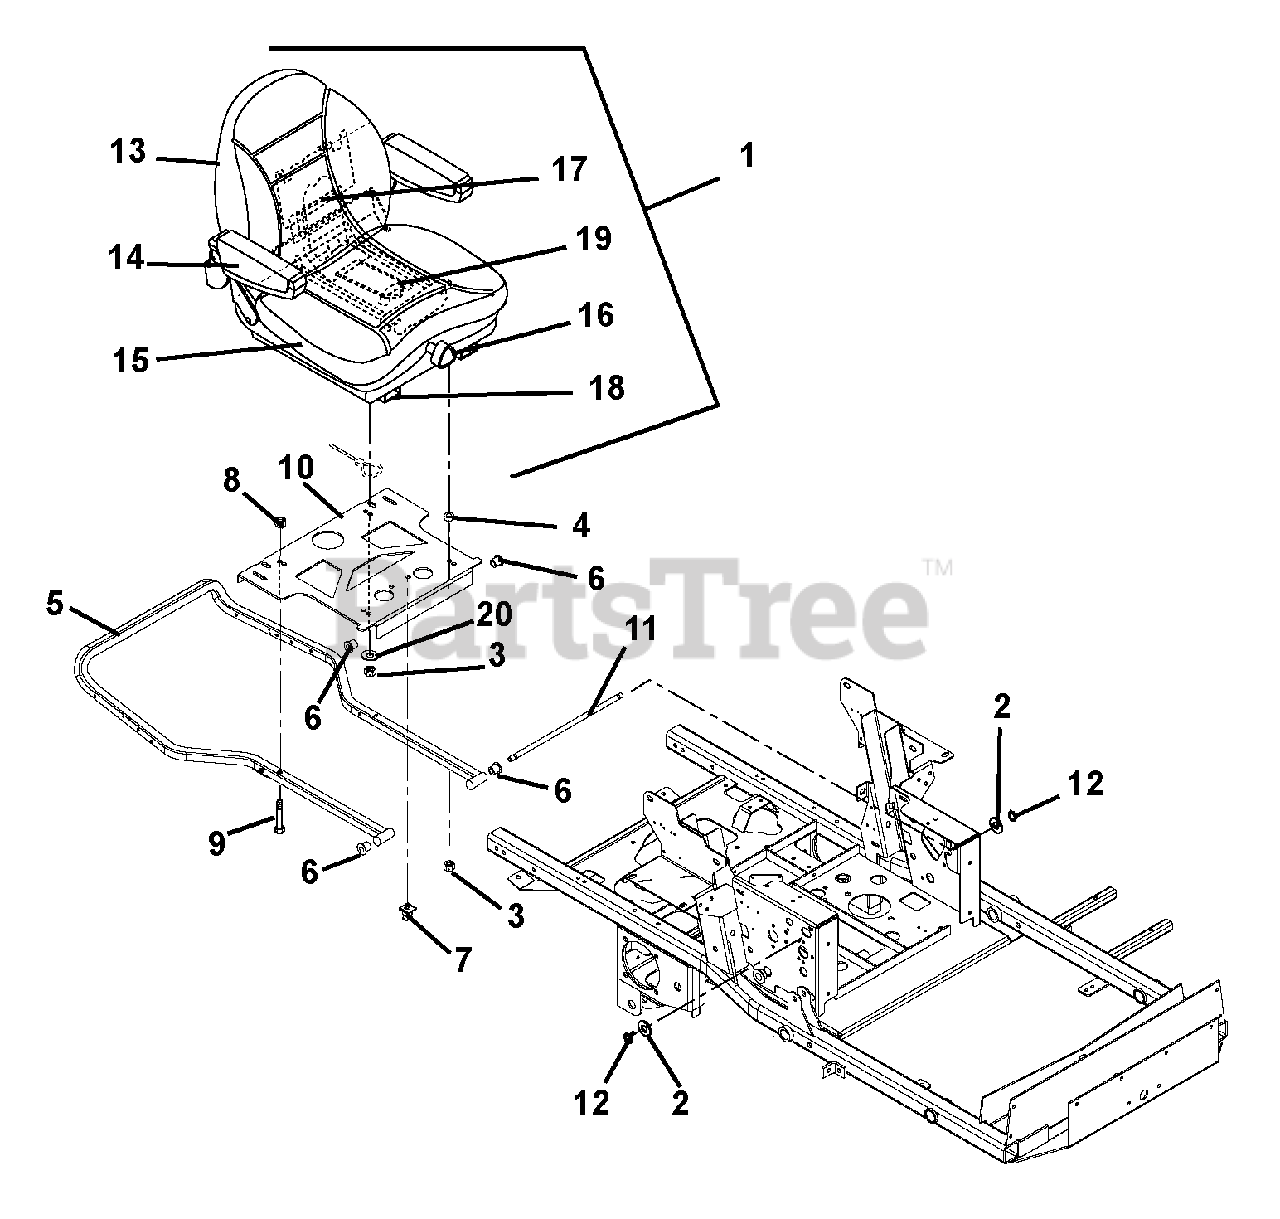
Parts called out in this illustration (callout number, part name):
1	Seat, Suspension, Light Gray
2	Washer, Flat Steel .531 x 1.06 x .095
3	Nut, Locking Top Flange .31-18
4	Bushing, Sleeve .377 x .624 x .235
5	Weldment, Hood Frame
6	Bushing-Flange .515 x .750 x .745 x 1.00
8	Nut, Locking Top Flange .38-16
9	Bolt, Rib Neck .38-16 x 1.50
10	Weldment, Seat Pivot Plate
11	Rod, Seat Frame Pivot
12	Ring, Retaining External .500 x .050
13	Kit, Back Cushion, Light Gray
15	Kit, Seat Cushion, Light Gray
16	Kit, Seat Knobs
17	Kit, Seat Back
18	Kit, Seat Slides
19	Kit, Seat, Spring and Saddle
20	Washer, Flat Steel .344 x 1.25 x .135
